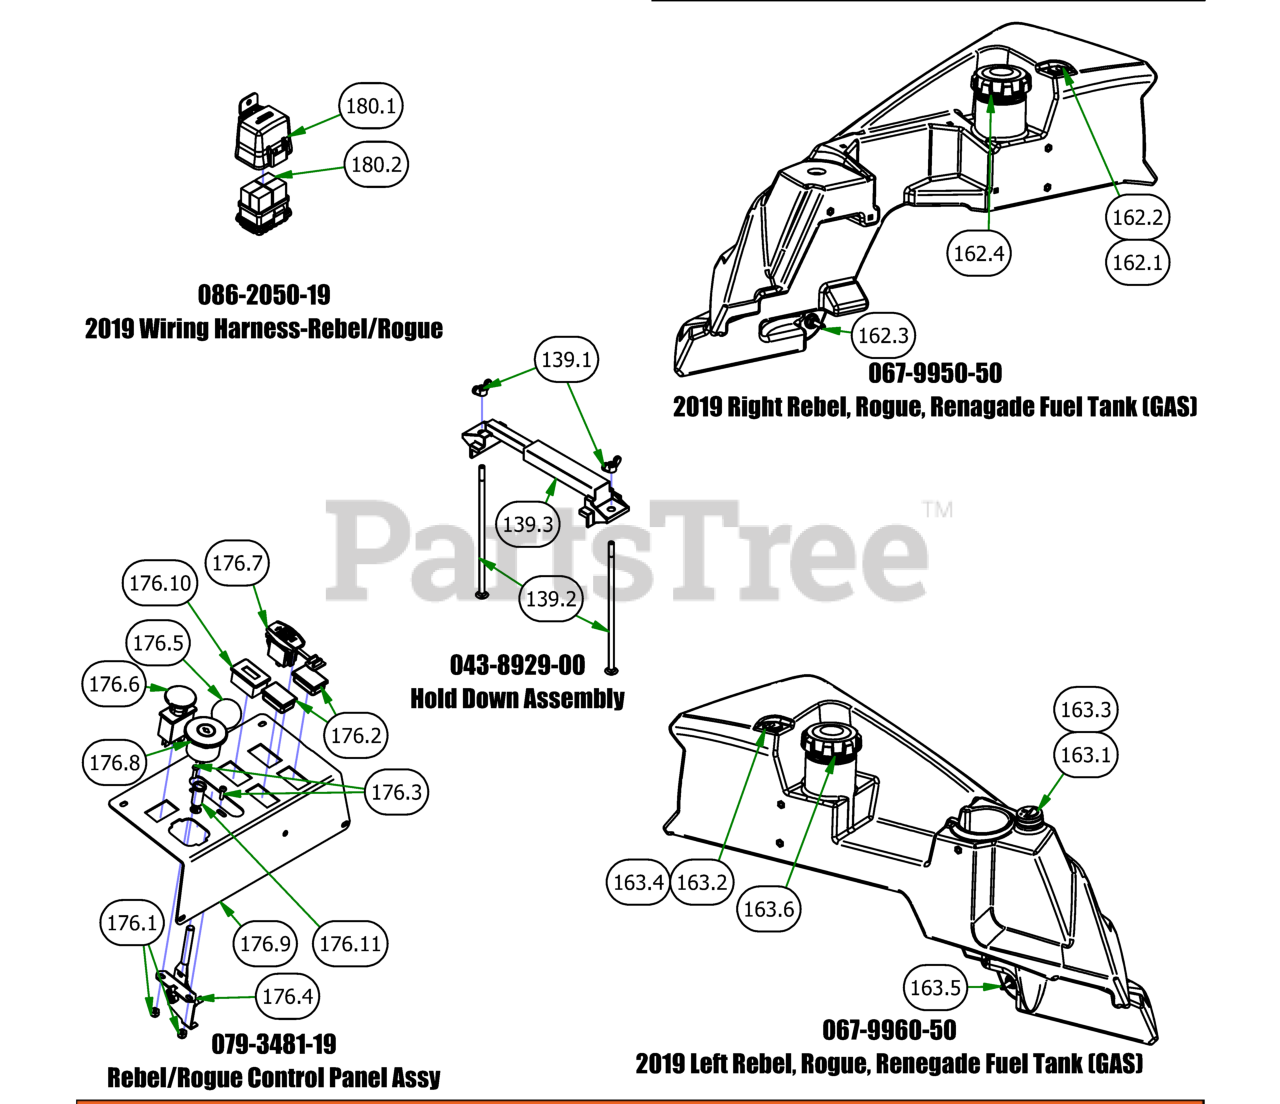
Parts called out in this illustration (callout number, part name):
139.1	1/4" Wing Nut
139.2	1/4-20 X 8 Carriage Bolt
139.3	Battery Hold Down
162.1	Roll Over Valve Grommet
162.2	Rollover Valve
162.3	Fuel Pick-up
163.1	Fuel Gauge with Grommet
163.2	Roll Over Valve Grommet
163.3	Fuel Gauge Grommet
163.4	Rollover Valve
163.5	Fuel Pick-up
176.1	10-24 Nylon Insert Locknut Zinc Orange Nylon
176.2	Light Plug
176.3	10-24 X 5/8 BS Button Head Bolt
176.4	Universal Throttle
176.5	Throttle Knob
176.6	PTO Switch
176.8	Ignition Switch
176.9	2019 Outlaw Control Panel
176.10	Tachometer
180.1	Relay Block Cover Replacement Kit
